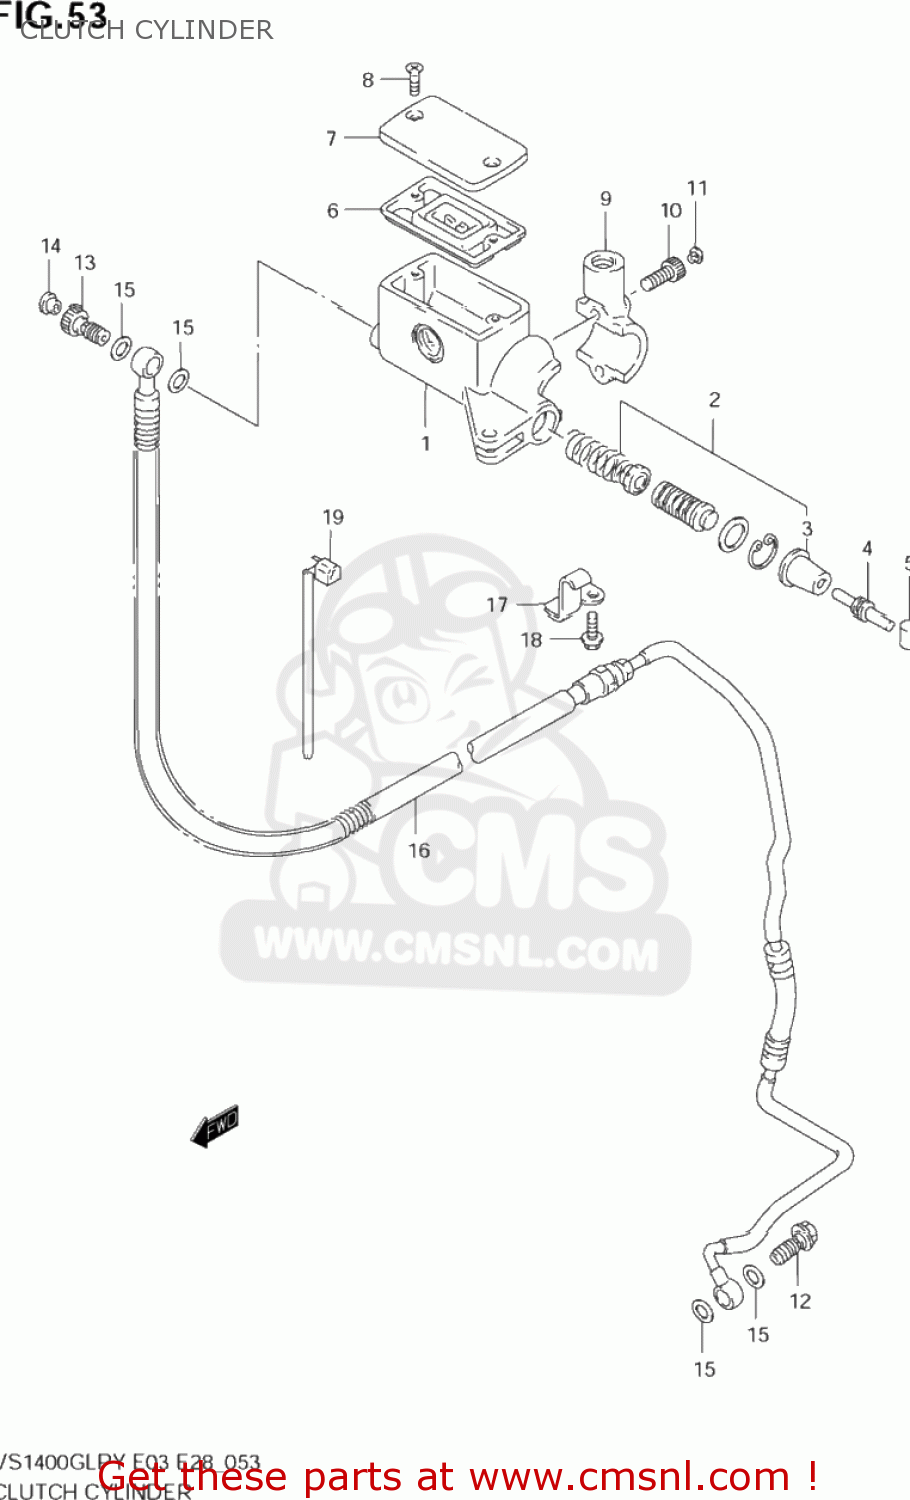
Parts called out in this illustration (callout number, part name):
1	CYLINDER ASSEMBLY,CLUTCH MASTER
2	PISTON & CUP SET
3	BOOT
4	PUSH ROD
5	BUSH
6	7
7	CAP
8	SCREW
9	HOLDER
10	BOLT
11	CAP(OD:10)
12	BOLT UNION
13	BOLT UNION
14	CAP(OD:12)
15	WASHER(10X15X1.5)
16	HOSE ASSY,CLUTCH
17	CLAMP,CLUTCH HOSE
18	BOLT
19	CLAMP(L:165)
